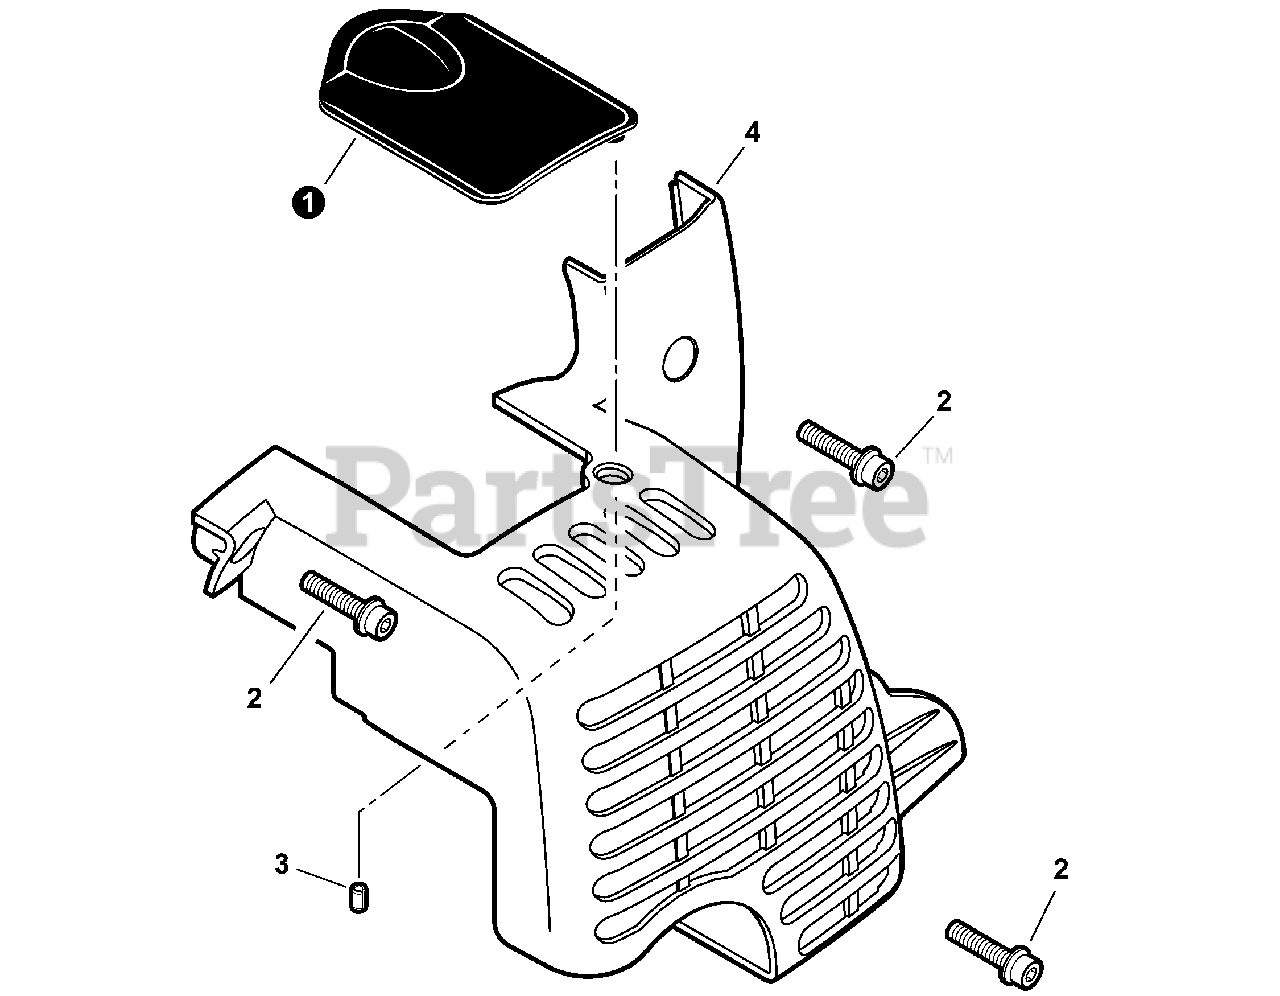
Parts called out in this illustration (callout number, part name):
1	COVER, SPARK PLUG
2	BOLT M5×20
3	PIN, SPRING 4×8
4	COVER, ENGINE
